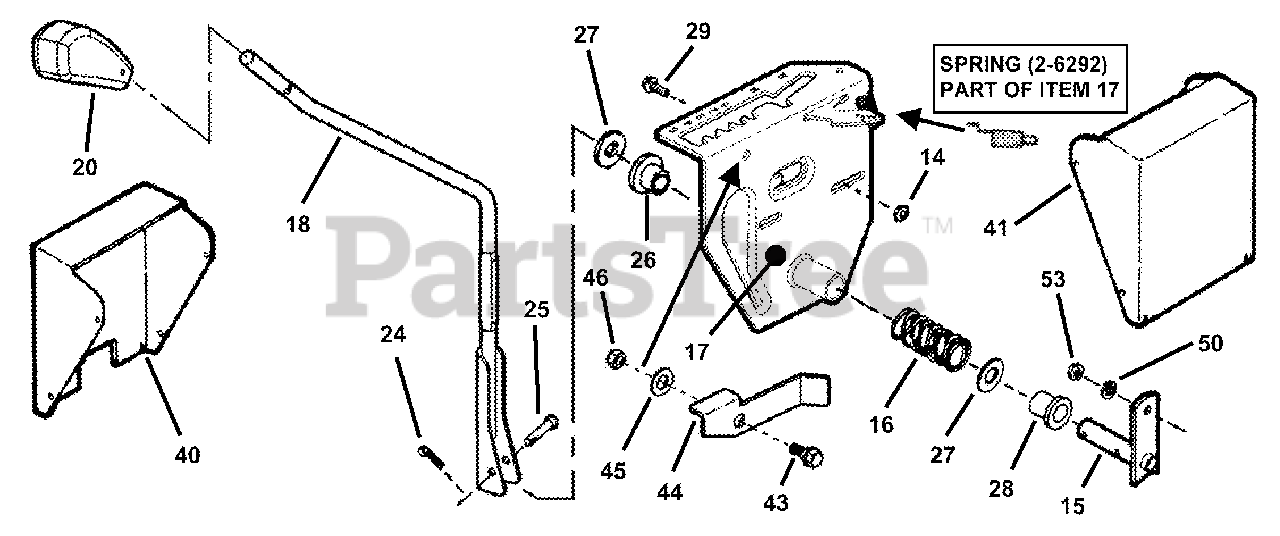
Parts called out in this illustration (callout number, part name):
14	NUT, 5/16-18 Hex, Gr. 5 or B
15	ARM, Shift Handle (weldment)
16	SPRING, Shift Handle
17	ASSEMBLY, Shift Detent
18	HANDLE, Shift (weldment)
20	GRIP, Shift Handle
24	PIN, 3/32 x 3/4" Cotter
25	PIN, 1/4 x 1-3/4" Tapered Clevis
26	BUSHING, Nylon
27	WASHER, Thrust
28	BUSHING, Nylon
29	SCREW, 5/16-18 x 5/8" Self Tap
40	COVER, Switch
41	COVER, Battery
43	BOLT, 5/16-18 Shoulder
44	LEVER, Over-Ride
45	WASHER, 7/16" Flat
46	NUT, 5/16-18 Nyloc
50	WASHER, 5/16" Split Lock
53	NUT, 5/16-24 Hex, Grade 5
